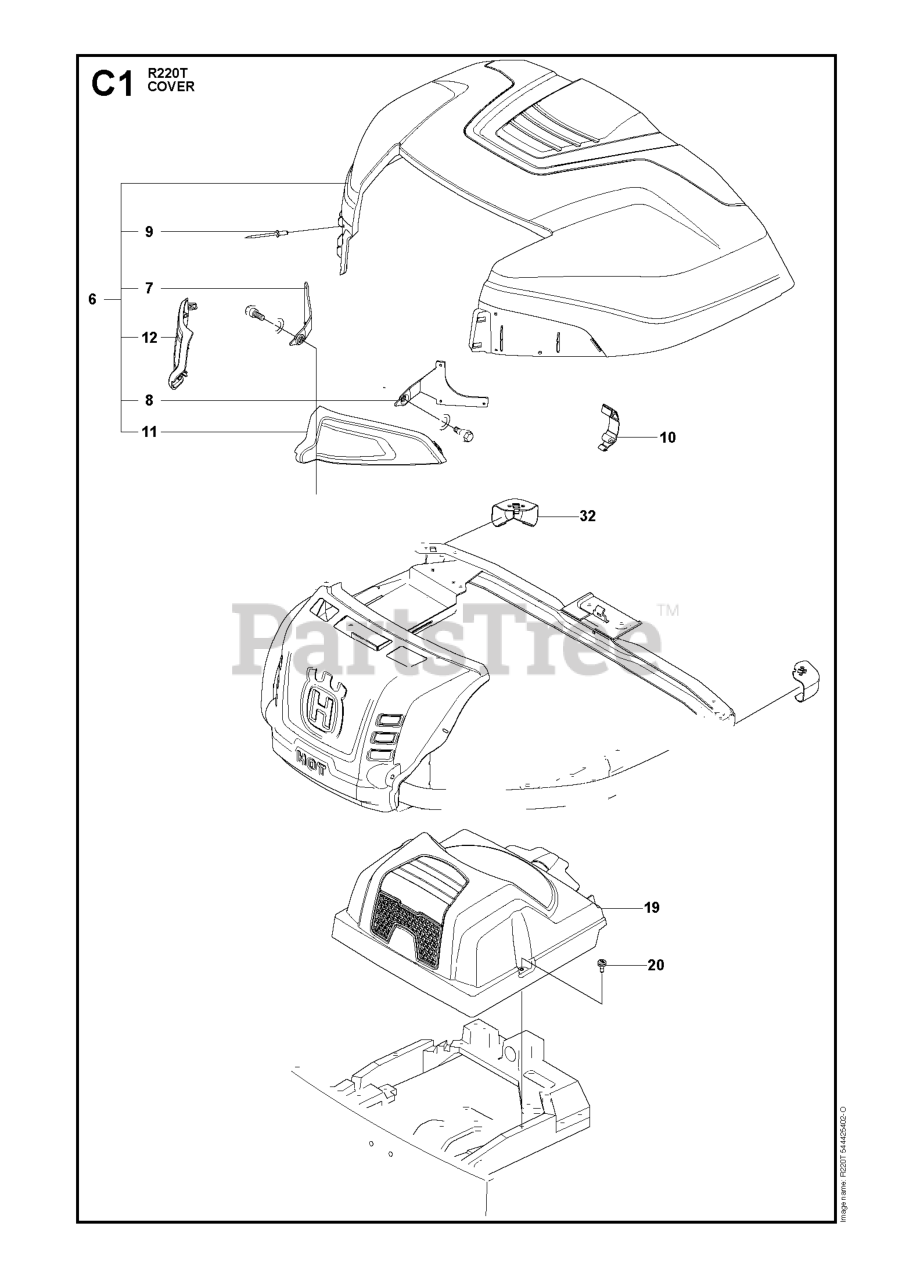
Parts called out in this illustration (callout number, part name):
6	ENGINE HOOD ASSY
10	CLIP GRAY
19	TRANSMISSION COVER
